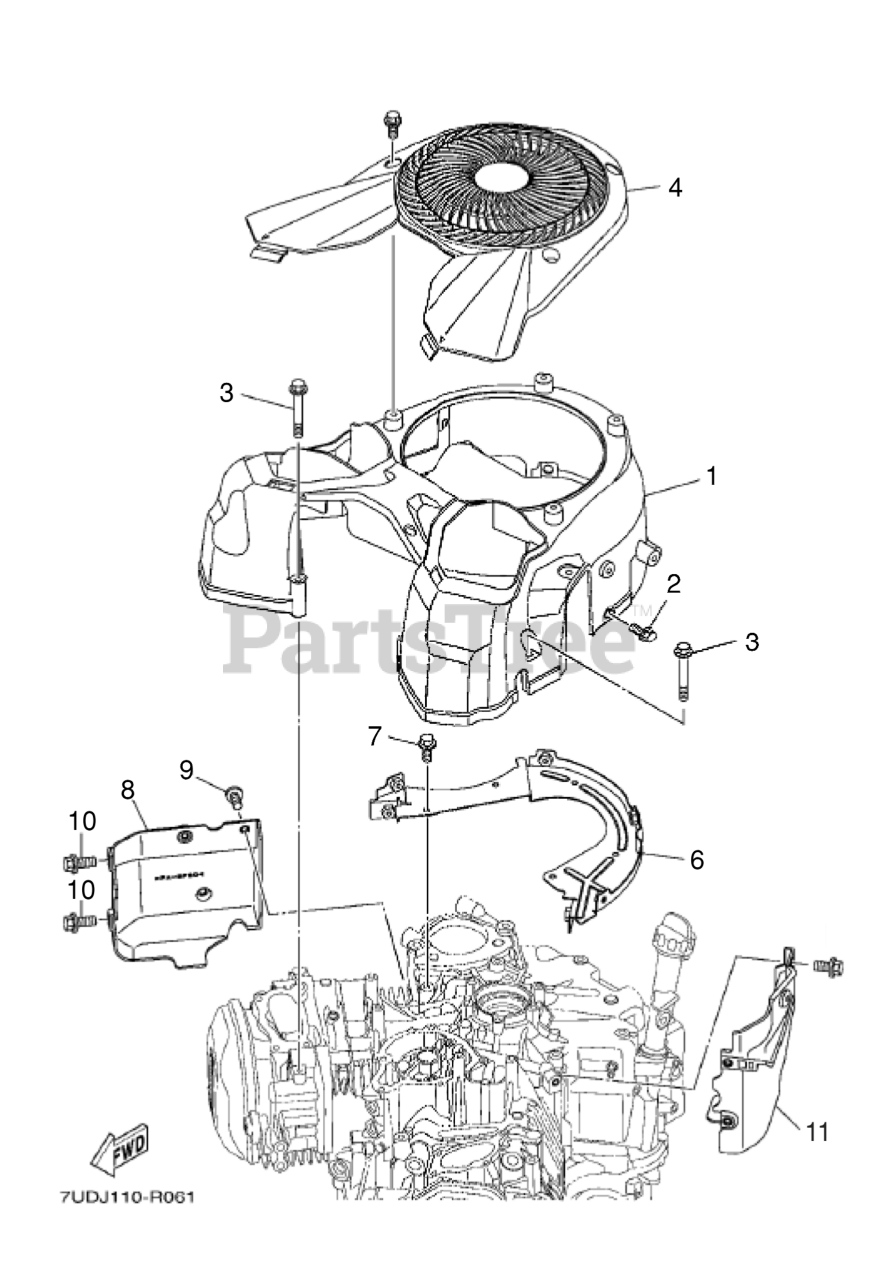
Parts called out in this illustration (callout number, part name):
1	CASE FAN YAMAHA PN: 7UD-E2621-
2	BOLT YAMAHA PN: 90109-06190
3	BOLT YAMAHA PN: 95802-06055
4	COVER FAN CASE YAMAHA PN: 7UD
6	SCROLL AIR SHROUD YAMAHA PN: 7
7	BOLT YAMAHA PN: 95802-06014
8	SHROUD SHROUD, CYLINDER 1
9	BOLT YAMAHA PN: 95802-06010
10	BOLT YAMAHA PN: 95802-06016
11	SHROUD SHROUD, CYLINDER 3
